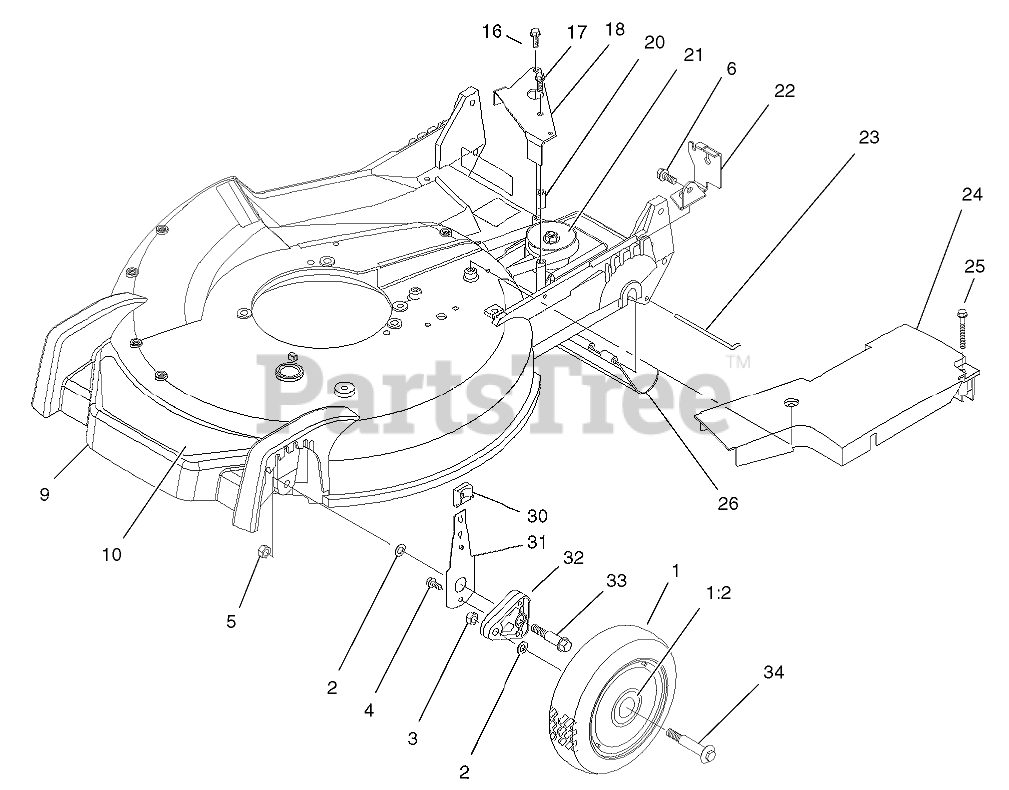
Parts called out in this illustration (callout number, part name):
1	WHEEL ASM
1:2	BUSHING
2	WASHER
4	SCREW-HWH
5	NUT-LOCK
6	SCREW-HWHTF
9	HOUSING ASM
10	DECAL-DECK
16	SCREW-HWHTF
17	SCREW-HWHTF
18	BRACKET-TRANSMISSION ACTUATOR
20	BUSHING-PLATE, ACTUATOR
21	GEAR CASE ASM
22	BRACKET-CABLE, TRACTION
23	ROD-SHIELD
24	COVER-BELT
25	Screw-HH (only on: 20784)
25	Screw-HH (only on: 20783)
26	SHIELD-TRAILING
30	KNOB-ARM
31	FRONT SPRING ARM ASM
32	ARM-PIVOT, FRONT
33	BOLT-SHOULDER
34	BOLT-SHOULDER
